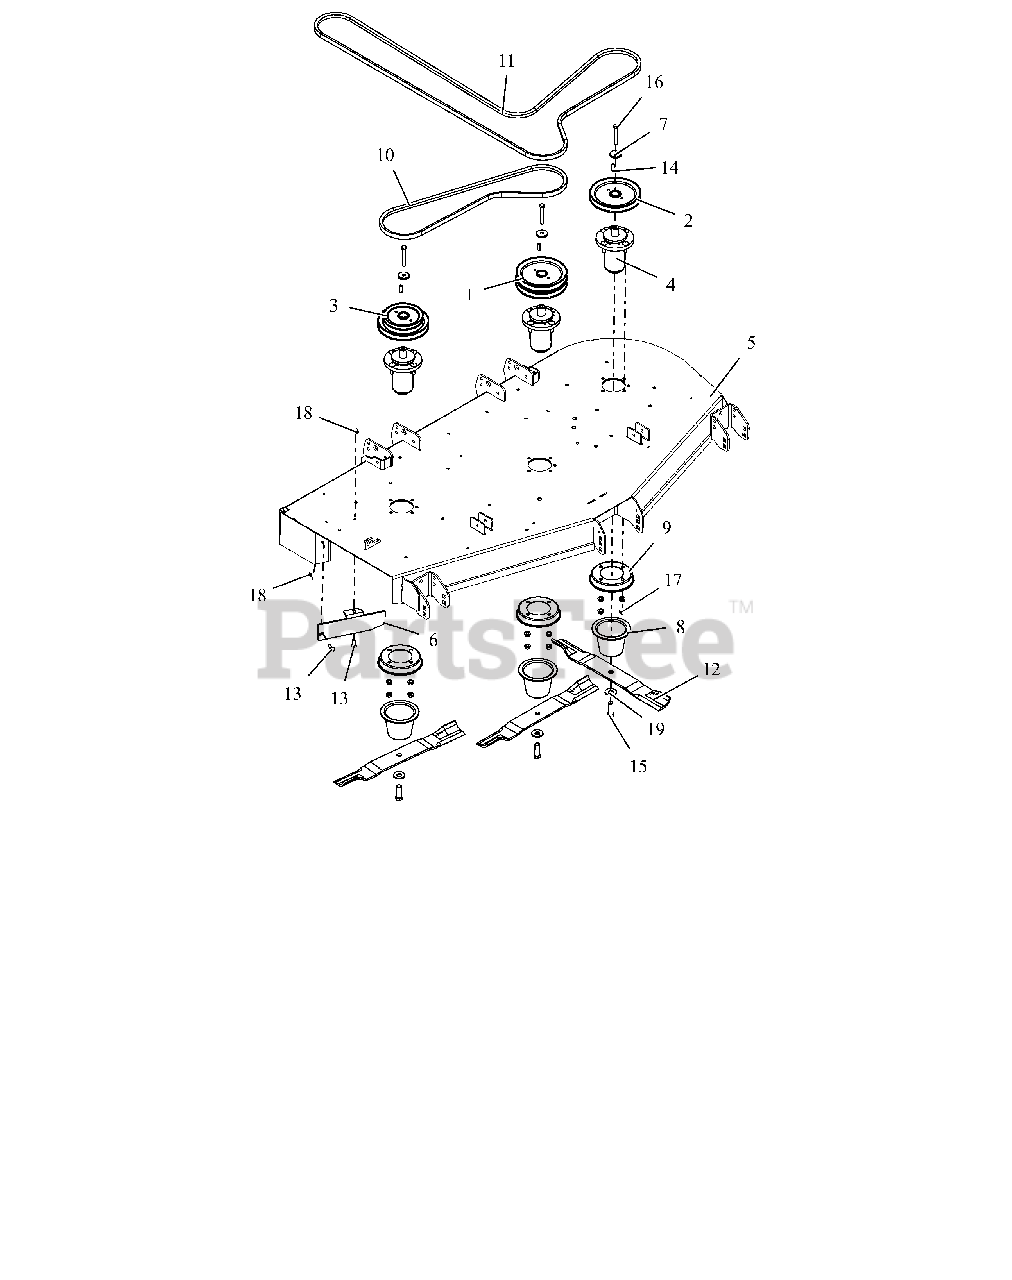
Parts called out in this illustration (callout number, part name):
1	PULLEY, DOUBLE-1"ID X 6.75"OD
2	PULLEY, V-1" ID X 6.75" OD
3	PULLEY, DBL-1"IDX6.75"&5.25"OD
4	ASM, MAINT FREE ALUM SPINDLE
5	DECK, PT60 W/SAFETY DECALS
6	60" DISCHARGE BAFFLE - RED
7	RETAINER, SHEAVE
8	GUARD, SPINDLE LOWER
9	GUARD, SPINDLE TOP
10	V-BELT, B-COGGED
11	BELT, B-SECTION EPDM RAW EDGE
12	BLADE, MOWER (20.50")
13	@BLT-RDHDSQNK .31-18X1.00 G5YZ
14	KEY, SQ .25X.25X1.00 RC 40-50
15	BLT, HEX .62-18X1.75 G8 ZCC
16	BLT, HEX .38-16X2.75 G8 ZCC
17	NUT-LK-CTR-FLG .375-16 GF ZCC
18	@NUT-LK-NYL-FLG .31-18 YWZC
19	WSHR-BLVL .669X1.535X.138
